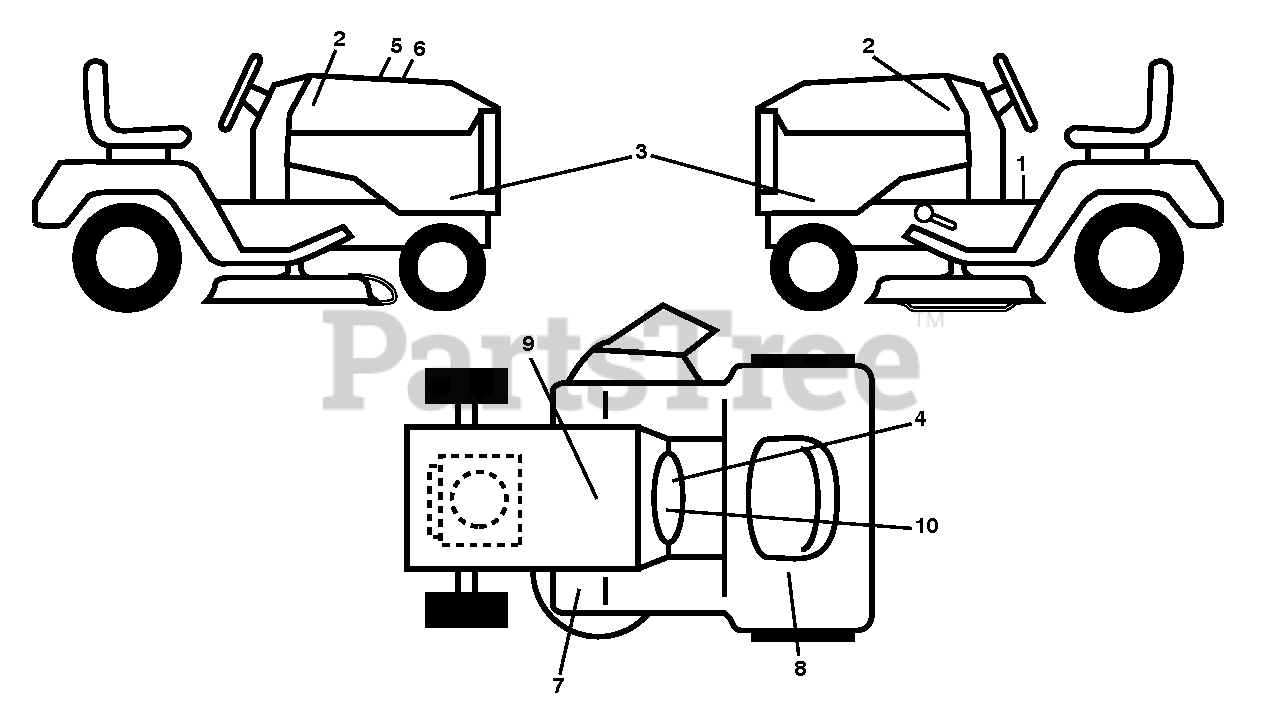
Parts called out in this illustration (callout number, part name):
1	DECAL.FENDER.WARNING
2	RP.DECAL.BADGE.170MM.TEXTLOGO
3	DECAL.SDPNL.HUSQGT2.MS668.YTH2
4	DECAL, WARNING SPARK ARRESTOR
5	DECAL.WARNING.CUST.RESP.E85.
7	DECAL.PEDAL.HUSQ.CROWN
8	DECAL.WARN.RESERVE.FUEL
9	DECAL BTRY SYMBOLS
10	LABEL.EMISS.CA.HUSQ/LOWES.2011
